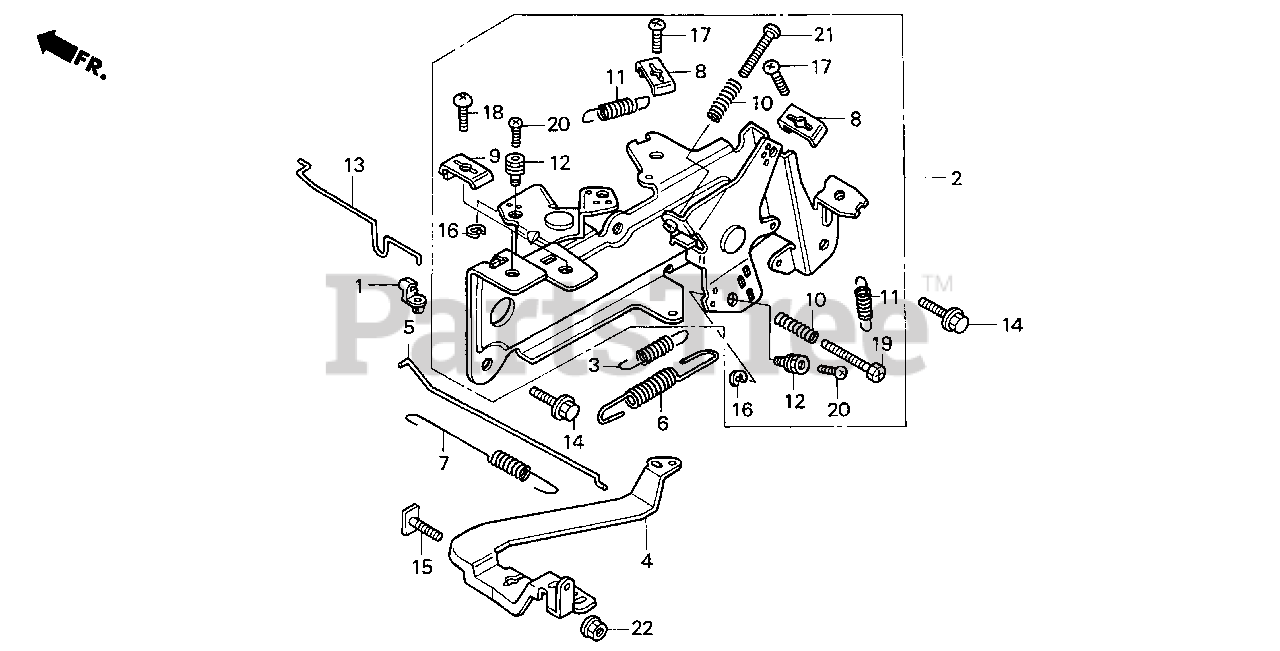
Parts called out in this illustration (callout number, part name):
1	JOINT, ROD
2	CONTROL ASSY.
3	SPRING, STARTER
4	ARM, GOVERNOR
5	ROD, GOVERNOR
6	SPRING, GOVERNOR
7	SPRING, THROTTLE RETURN
9	HOLDER, CABLE
10	SPRING, CONTROL ADJUSTING
11	SPRING, CABLE RETURN
13	ROD, CHOKE CONTROL
14	BOLT, FLANGE (6X14)
15	BOLT, GOVERNOR ARM
18	BOLT, SLOT (5X16)
19	BOLT, SLOT (5X25)
21	SCREW, PAN (5X25)
22	NUT, FLANGE (6MM)
